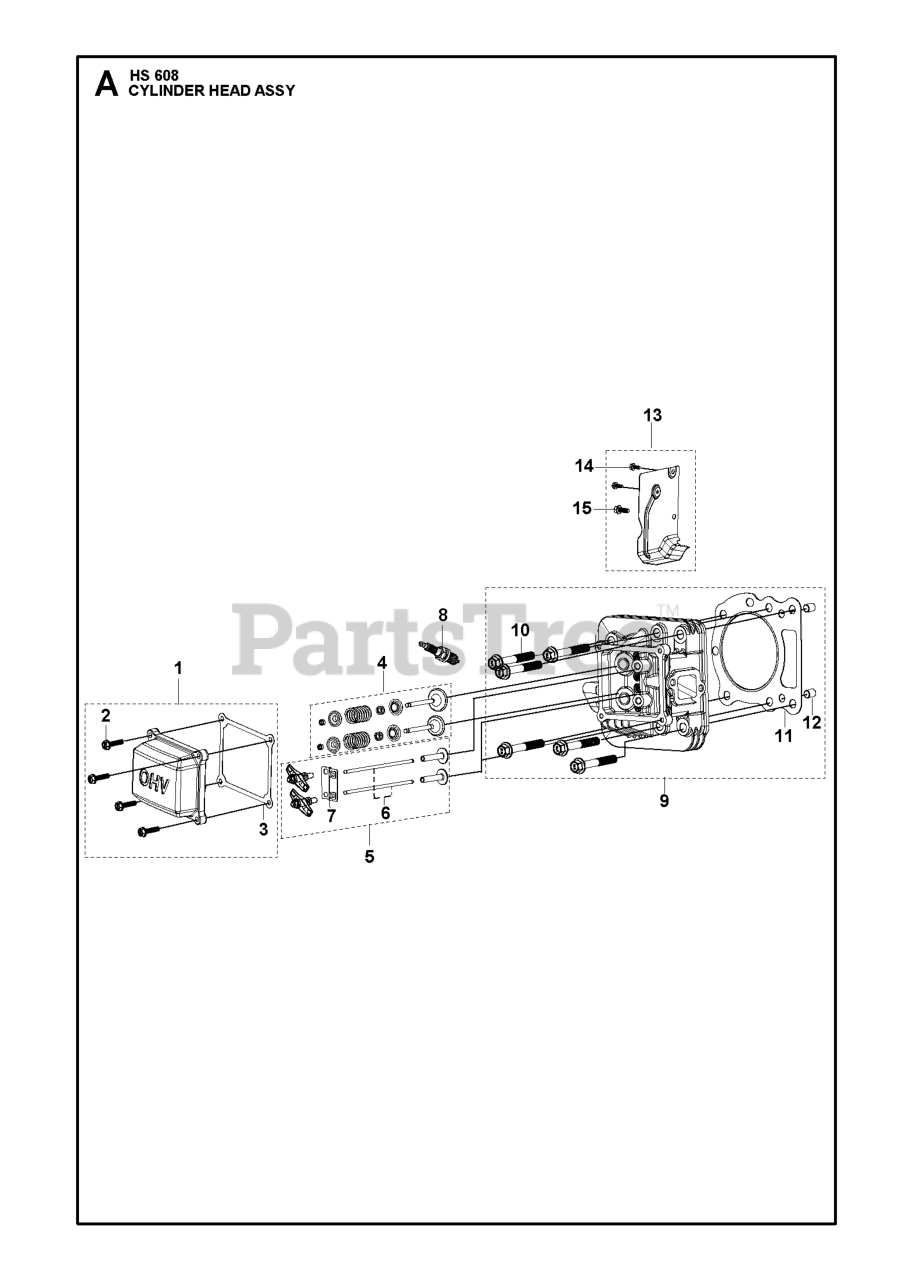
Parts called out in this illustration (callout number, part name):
1	CYLINDER COVER CYLINDER HEAD C
2	BOLT GB/T 5789: M6 L=25
3	GASKET CYLINDER HEAD COVER GAS
4	VALVE KIT.
5	VALVE KIT ROCKER ARM KIT
6	PUSH ROD PUSH ROD SET
7	PLATE PUSH ROD GUIDE PLATE
8	SPARK PLUG HQT-7 RESISTOR
9	CYLINDER HEAD KIT
10	Husqvarna TBD
11	GASKET CYLINDER HEAD GASKET
12	PIN LOCATION PIN
13	DEFLECTOR AIR DEFLECTOR KIT
